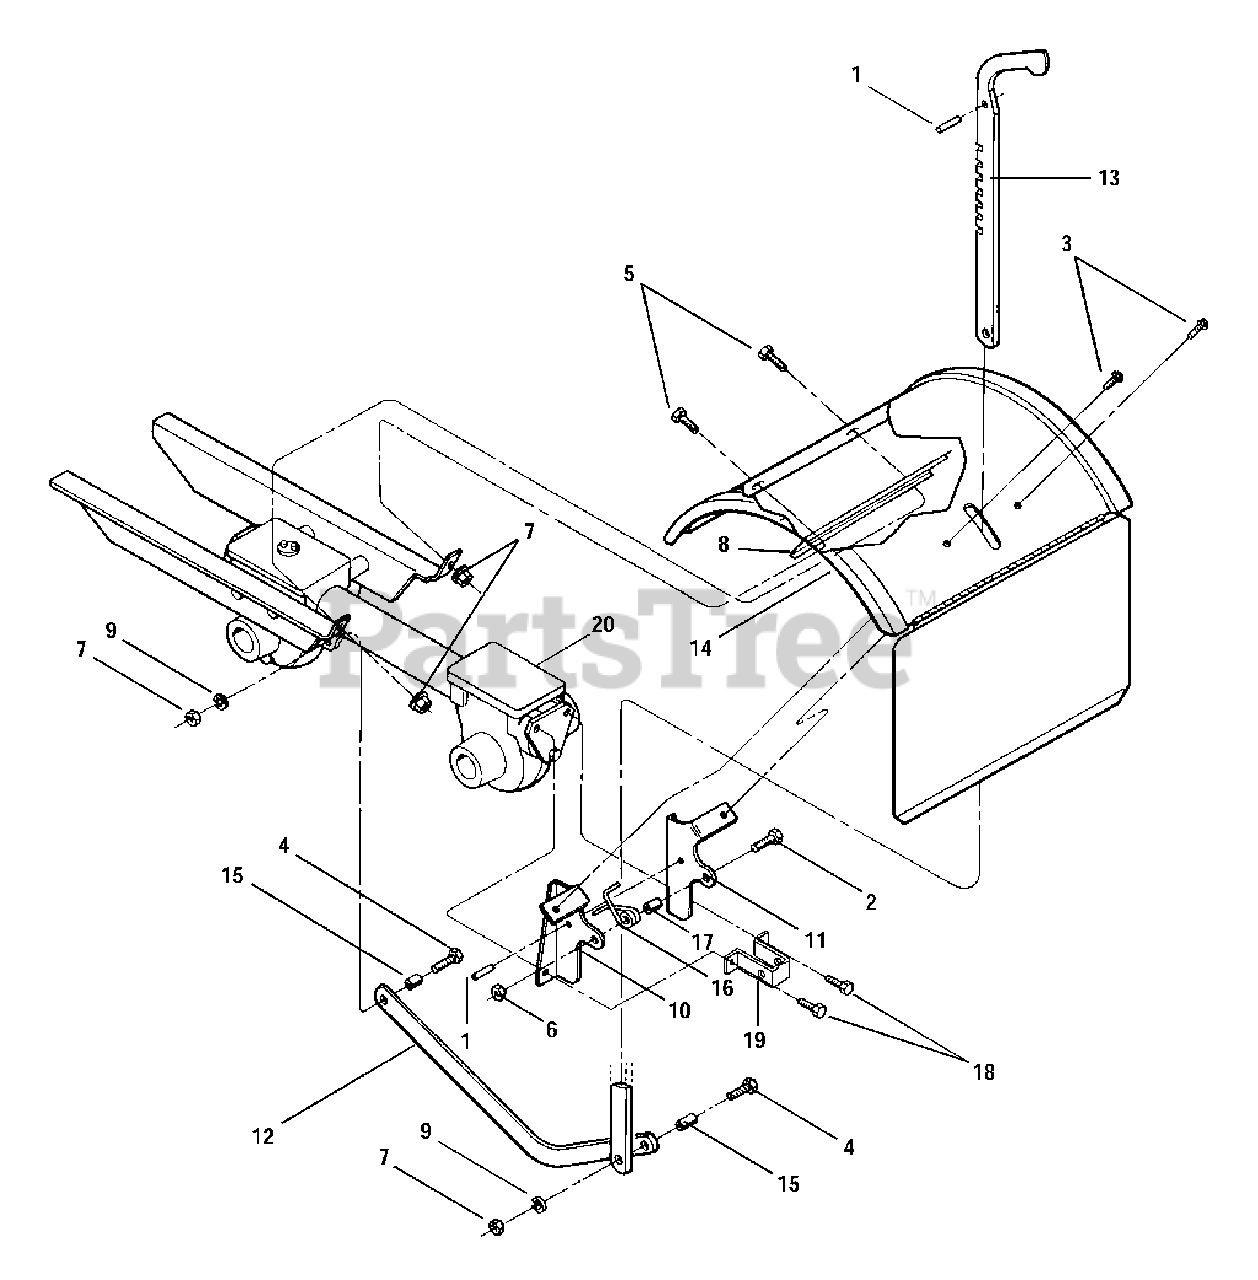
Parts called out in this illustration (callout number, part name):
1	Spirol Pin
2	Hex Hd. Screw, 1/4-20 x 1
3	Screw, Self-Tapping,1/4-20 x 1/2
4	Hex Hd. Screw, 5/16-18 x 1-1/4
5	Hex Hd. Screw, 5/16-18 x 3/4
6	Lock Nut, 1/4-20
7	Lock Nut, 5/16-18
8	Support Bracket
9	Lock Washer, 5/16
10	Hood Bracket, Left Hand
11	Hood Bracket, Right Hand
12	Drag Bar
13	Depth Regulator Lever
14	Tine Hood Assembly
16	Spring, Depth Regulator
18	Hex Hd. Flange Screw, 5/16-18 x 1
